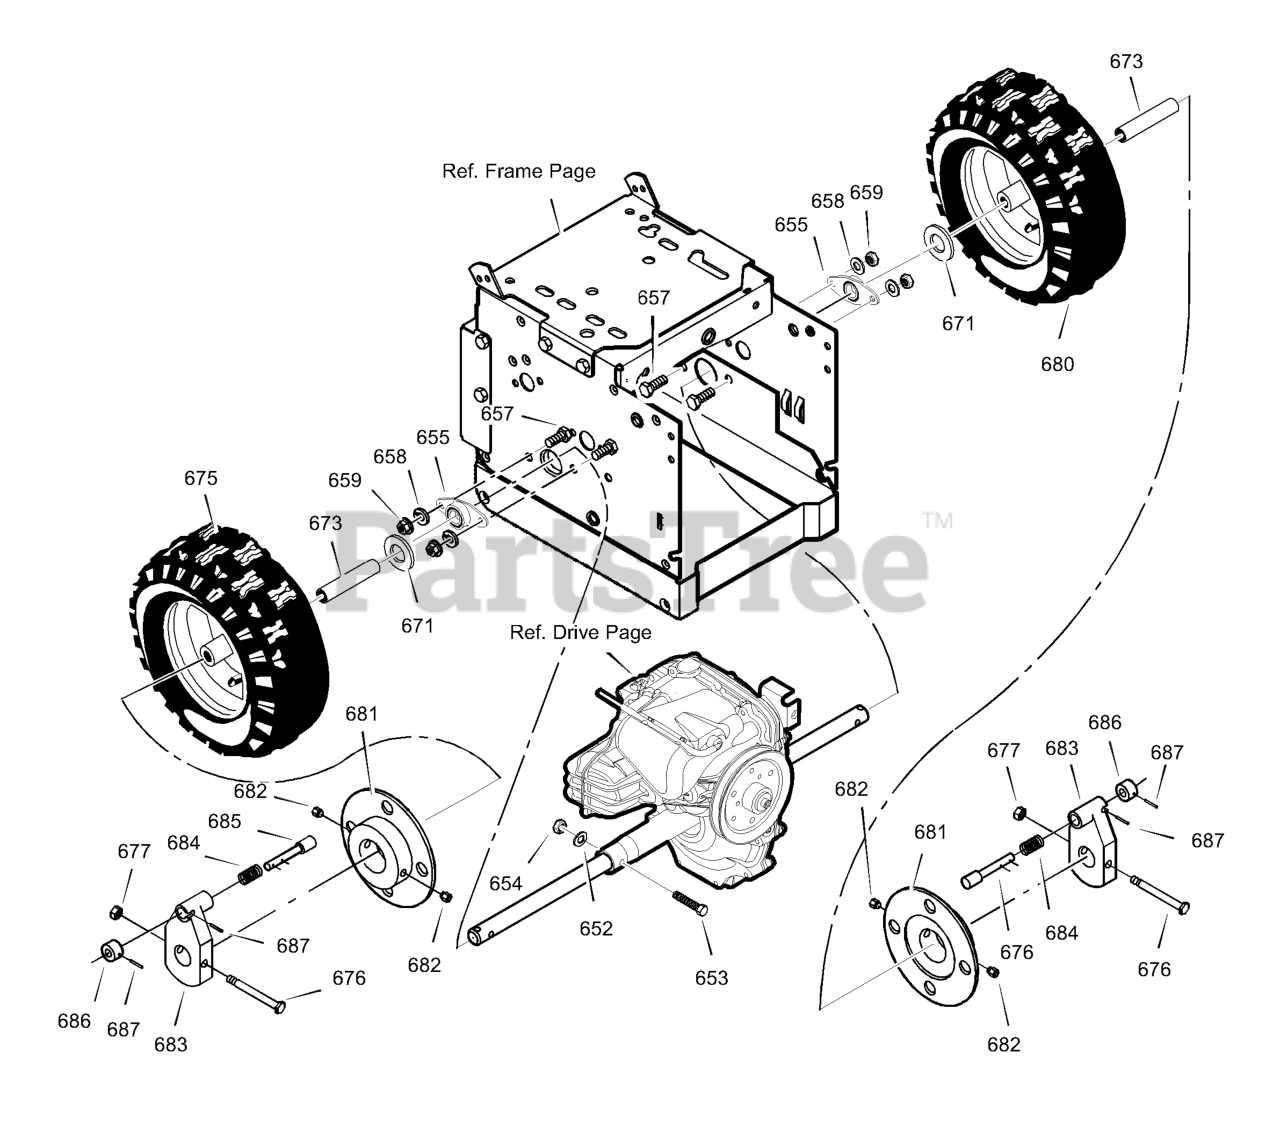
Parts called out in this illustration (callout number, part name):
653	SCREW, 1/4-20X1.75
654	NUT, 1/4-20
655	BEARING & RETAINER ASSY
657	SCREW, 3/8-16 x .75
658	WASHER, SPLTLK
659	NUT, 3/8-163
671	WASHER, FLAT
673	BUSHING, WHEEL
675	TIRE & RIM, RIGHT
676	SCREW, 1/4-20 X 2.25
677	NUT, 1/4-20
680	TIRE & RIM, LEFT
681	DISC, WHEEL
683	HUB, WHEEL LOCK
685	PIN, LOCK
